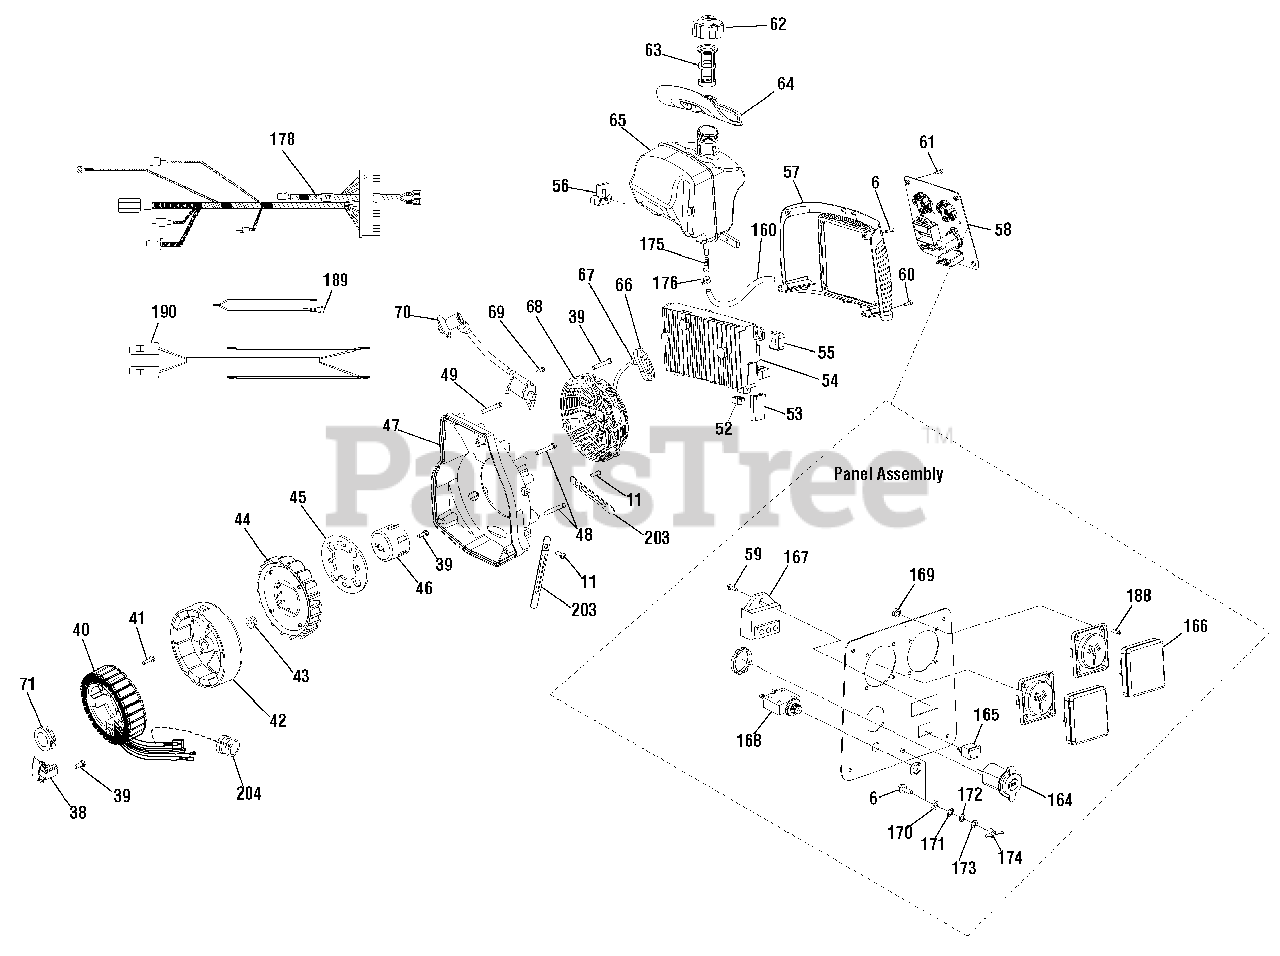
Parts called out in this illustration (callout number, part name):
11	SCREW
38	TRIGGER-IGNITION
39	SCREW
45	TERMINAL
47	COVER-FAN
48	BOLT
49	BOLT
52	MOUNT-VIBRATION
53	MOUNT-VIBRATION
55	MOUNT-VIBRATION
56	MOUNT-VIBRATION
59	SCREW
60	SCREW
61	SCREW
63	FILTER-FILLER NECK
64	PAD-FUEL TANK
67	GRIP
68	STARTER-REWIND
69	SCREW
71	SEAL-OIL
167	LIGHT-INDICATOR
168	BREAKER-CIRCUIT
169	NUT
170	NUT
171	WASHER
172	WASHER
173	WASHER
174	NUT
175	FILTER-FUEL TANK
176	CLAMP
188	SCREW
203	BRACKET
204	COVER-RUBBER
